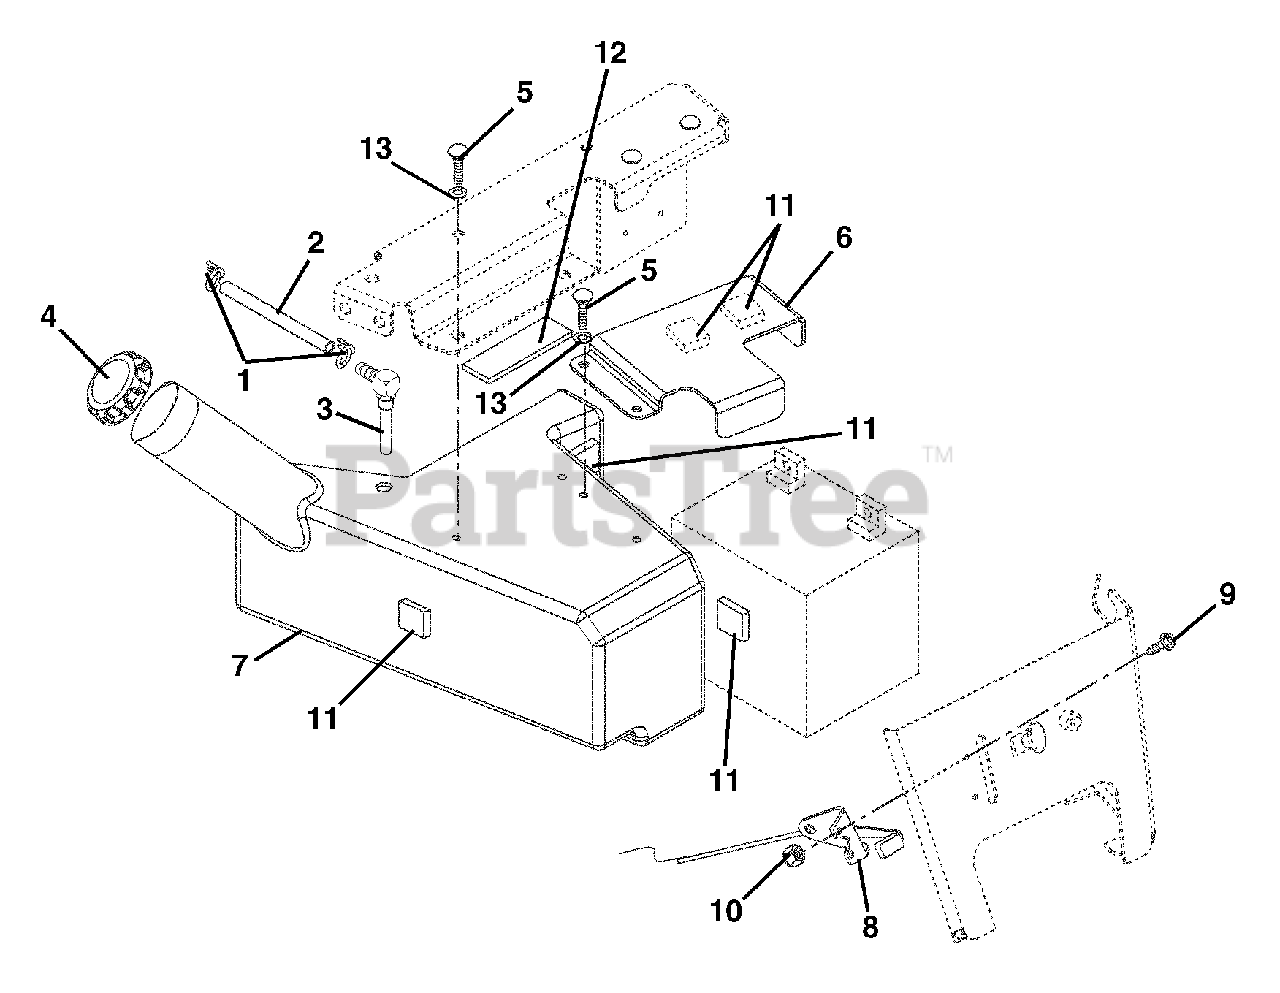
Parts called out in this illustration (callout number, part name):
1	CLAMP-HOSE WIRE .490/.510X.116
2	GAS LINE-BULK 1/4" I.D.
3	TANK FITTING
4	FUEL CAP
5	BLT-SERHFWH .25-20X.75 YWZC
6	BRACKET-BATTERY
7	TANK-FUEL
8	THROTTLE CABLE
9	@SCR-MCH 10-24X.50 HWH YWZC
10	@NUT-LK-NYL 10-24 W/INSRT YWZC
11	PAD, FOAM
12	VHB TAPE 4941F
13	@WSHR-LK .31X.078 REG YWZC
